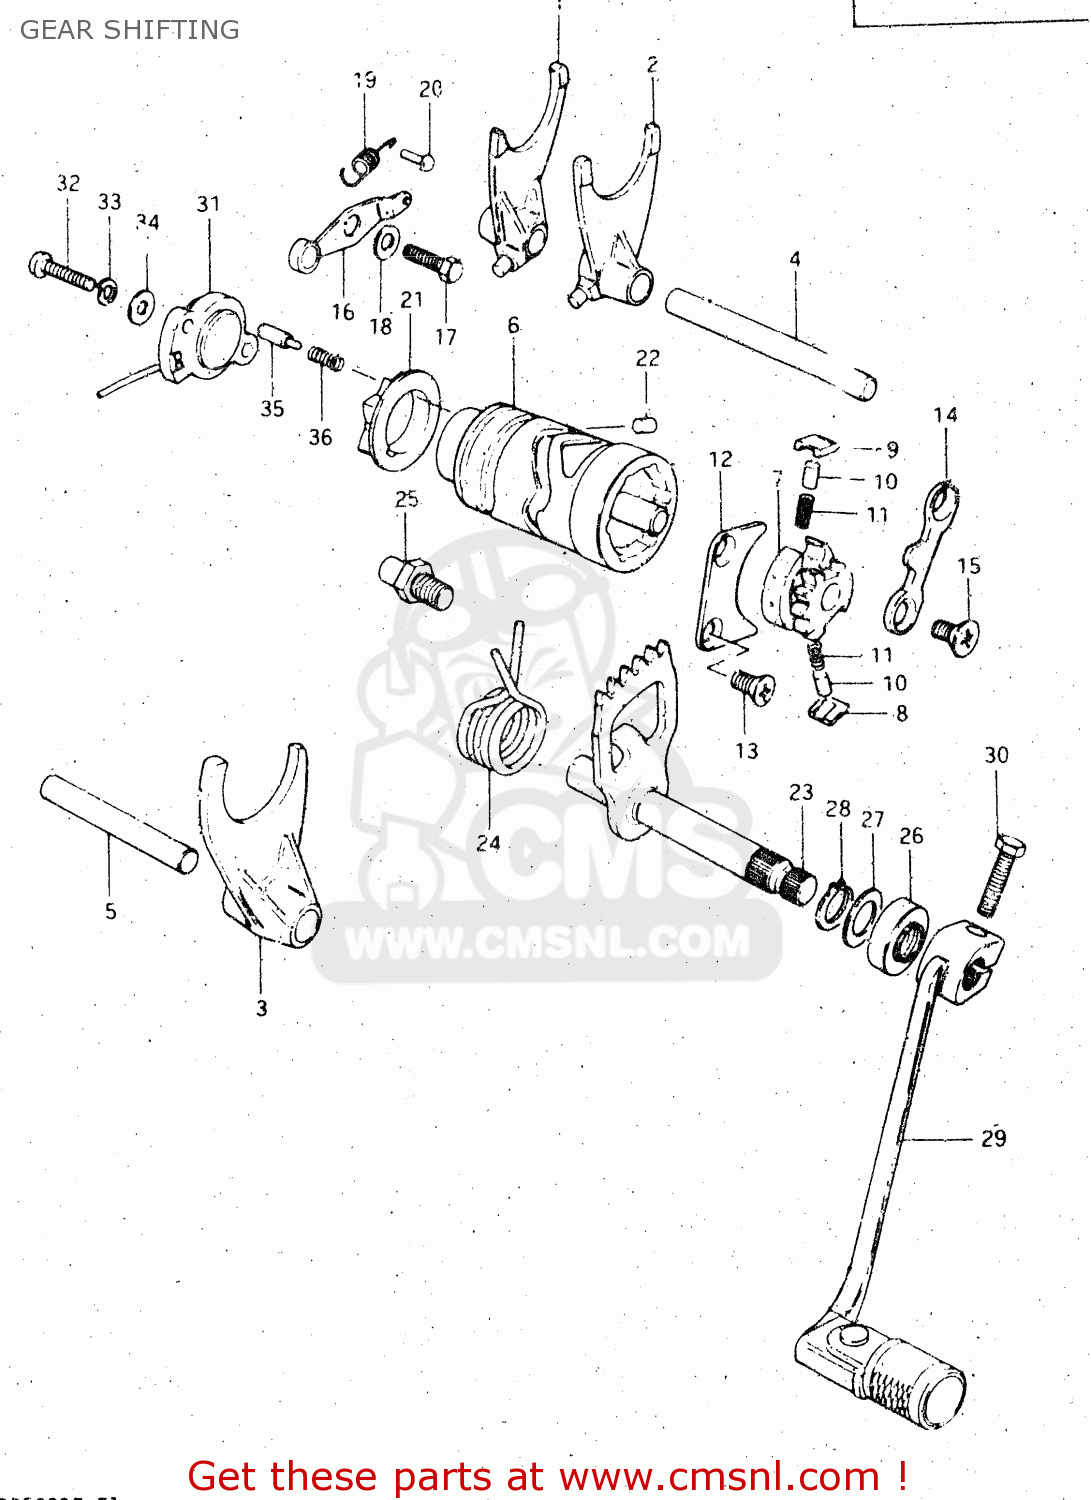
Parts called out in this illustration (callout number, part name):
1	FORK,GEAR SHIFT NO.1
2	FORK,GEAR SHIFT NO.2
3	FORK,GEAR SHIFT NO.3
4	SHAFT,GEAR SHIFT FORK
5	SHAFT,GEAR SHIFT FORK
6	CAM,GEAR SHIFT
7	GEAR,GEARSHIFT CAM DRIVE
8	PAWL,GEAR SHIFT NO.1
9	PAWL,GEAR SHIFT NO.2
10	PIN(5X8)
11	SPRING
12	LIFTER,GEAR SHIFT PAWL
13	SCREW
14	GUIDE,GEAR SHIFT CAM
15	SCREW
16	STOPPER,GEAR SHIFT CAM
17	BOLT
18	WASHER
19	SPRING
20	RIVET
21	PLATE,SHIFT CAM STOPPER
22	PIN 4X6
23	SHAFT,GEAR SHIFT
24	SPRING
25	STOPPER,GEAR SHIFT CAM
26	OIL SEAL
27	WASHER
28	CIRCLIP
29	LEVER ASSEMBLY,GEAR SHIFTING
30	BOLT
31	TERMINAL BASE,NEUTRAL
32	SCREW
33	LOCK WASHER
34	WASHER
35	PIN(5X15.5)
36	SPRING
